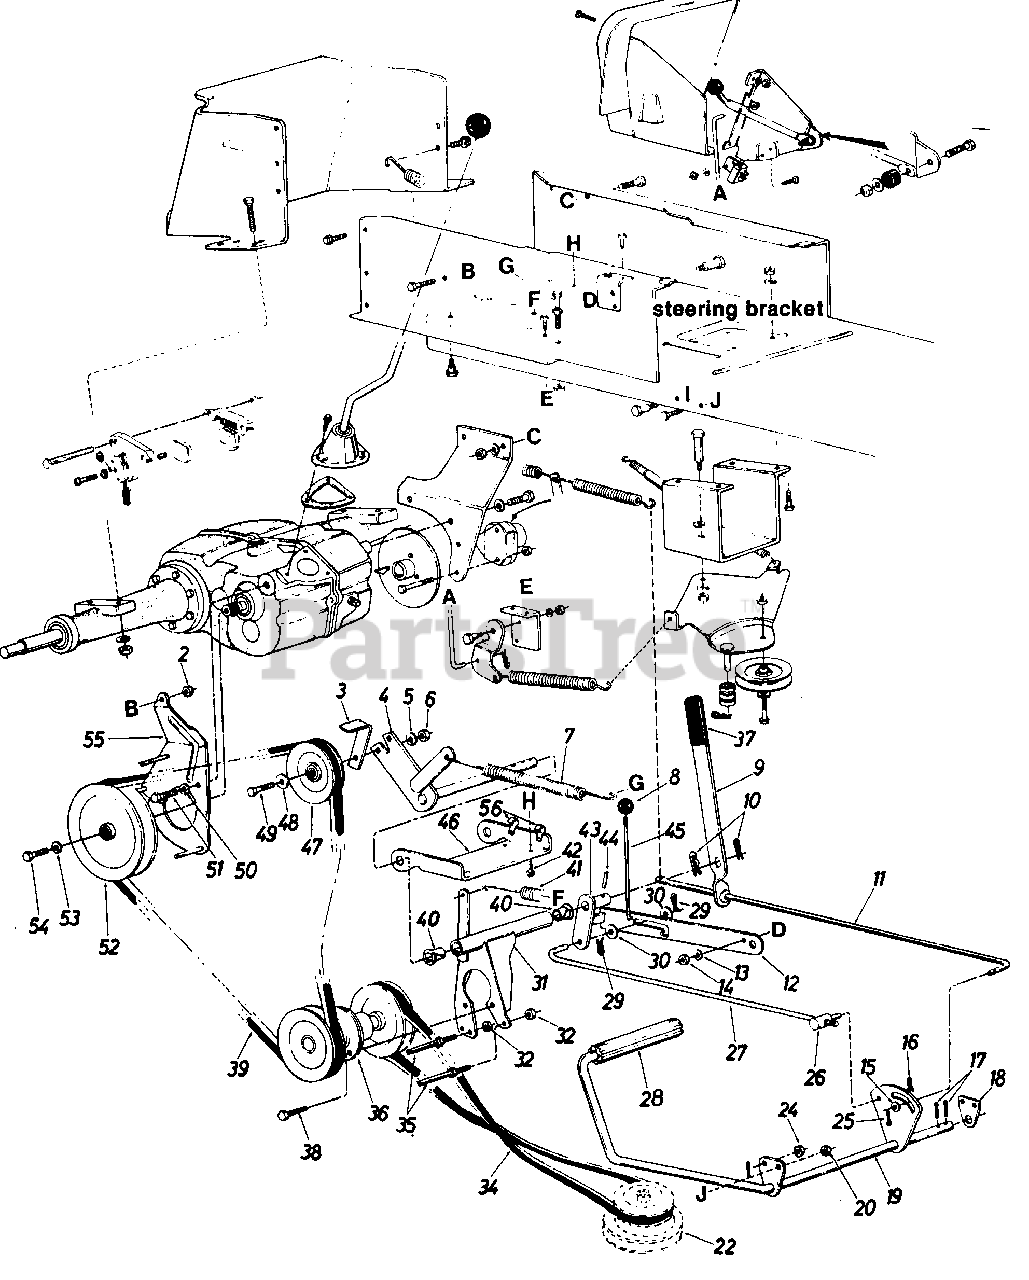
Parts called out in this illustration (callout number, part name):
2	Hex L-Nut 3/8-16 Thd.
5	L-Wash. 3/8" Scr.
6	Hex Nut 3/8-16 Thd.
7	Ext. Spring
8	Knob
9	Hand Brake Lever
10	Hairpin Cotter 5/8" Dia.
11	Brake Rod
12	Parking Brake Cam
13	Fl-Wash. 5/16" Scr.
14	Hex Nut 5/16-18 Thd.*
15	Fl-Wash. 5/16" Scr.
16	Hairpin Cotter 3/8 Rod
17	Cotter Pin 118" Dia. x 1.00" Lg.*
18	Clutch Rod Brg. Brk't.
19	Clutch Brake Pedal Ass'y.
20	Hex Cent. L-Nut 3/8-16 Thd.
22	Engine Pulley 4.75 & 5.56
24	Hex Cent. L-Nut 3/8-16 Thd.
25	Cotter Pin 3132" Dia. x .75" Lg.*
26	Pivot Bushing
27	Brake Cam Rod
28	Foot Pad
29	Hairpin Cotter 3/8 Rod
30	Fl-Wash. 3/8 I.D. x 1.00" O.D. x .030
31	Jack Shaft Mtg. Brk't. Ass'y.
32	Hex Top L-Nut 3/8-16 Thd.
34	"V"-Belt 1/2 x 59" Lg.
35	Stud 3/8-16 x 3.62" Lg. Special
36	Jack Shaft Ass'y.
37	Flat Grip
38	Hex Sem Scr. 5/16-18 x .75"
39	"V"-Belt 1/2 x 40" Lg. (Kevlar)
40	Nyliner 5/8" I.D. x .88" Lg.
41	Ext. Spring
42	Hex Thd. Rolling Scr. 1/4-20 x .50" Lg.
43	Clutch-Idler Horn Ass'y.
44	Spring Pin Spiral 1/4" Dia. x 1.00" Lg.
45	Parking Brake Link
46	Idler Mtg. Brk't. Drive
47	4" "V"-Idler Pulley
48	Fl-Wash. 3/8" I.D.
49	Hex Scr. 3/8-16 x 1.75" Lg.
50	L-Wash. 3/8 Scr.
51	Hex Scr. 3/8-16 x .75" Lg.
52	"V"-Pulley 7.0" O.D.
53	L-Wash. 3/8" Scr.
54	Hex Scr. 3/8-24 x .75" Lg.
55	Belt Guard Ass'y.
56	Plastic Hose Clamp
